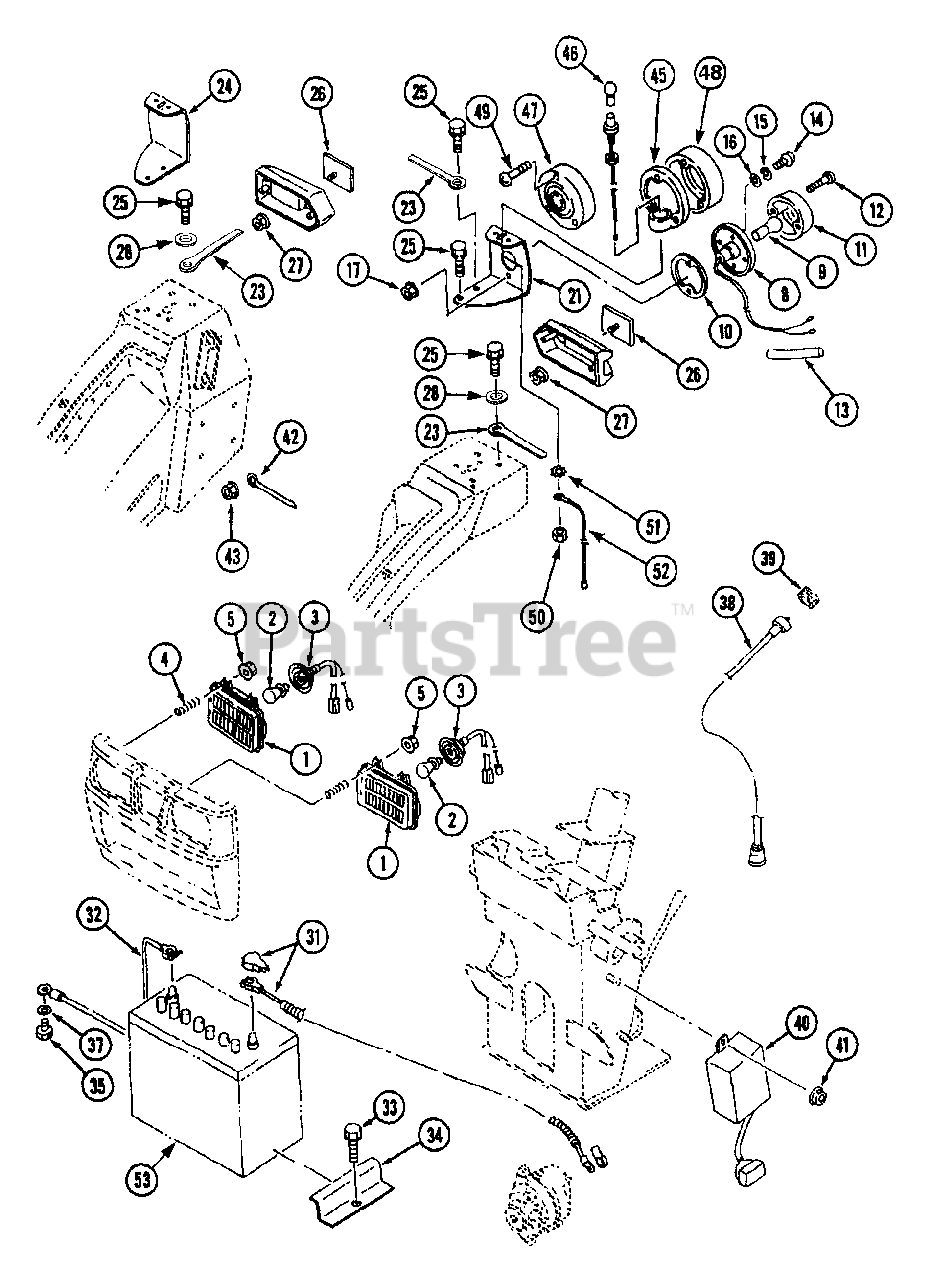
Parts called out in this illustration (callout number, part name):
1	Unit, Semi Sealed Beam
8	Socket
15	Washer, Spring
21	Bracket, Lamp L.H.
24	Bracket, Lamp R.H.
32	Cord, Battery
34	Clamp, Battery
38	Cable, Flexible
49	Screw
51	Washer, Tooth
53	Battery, 410CCA
